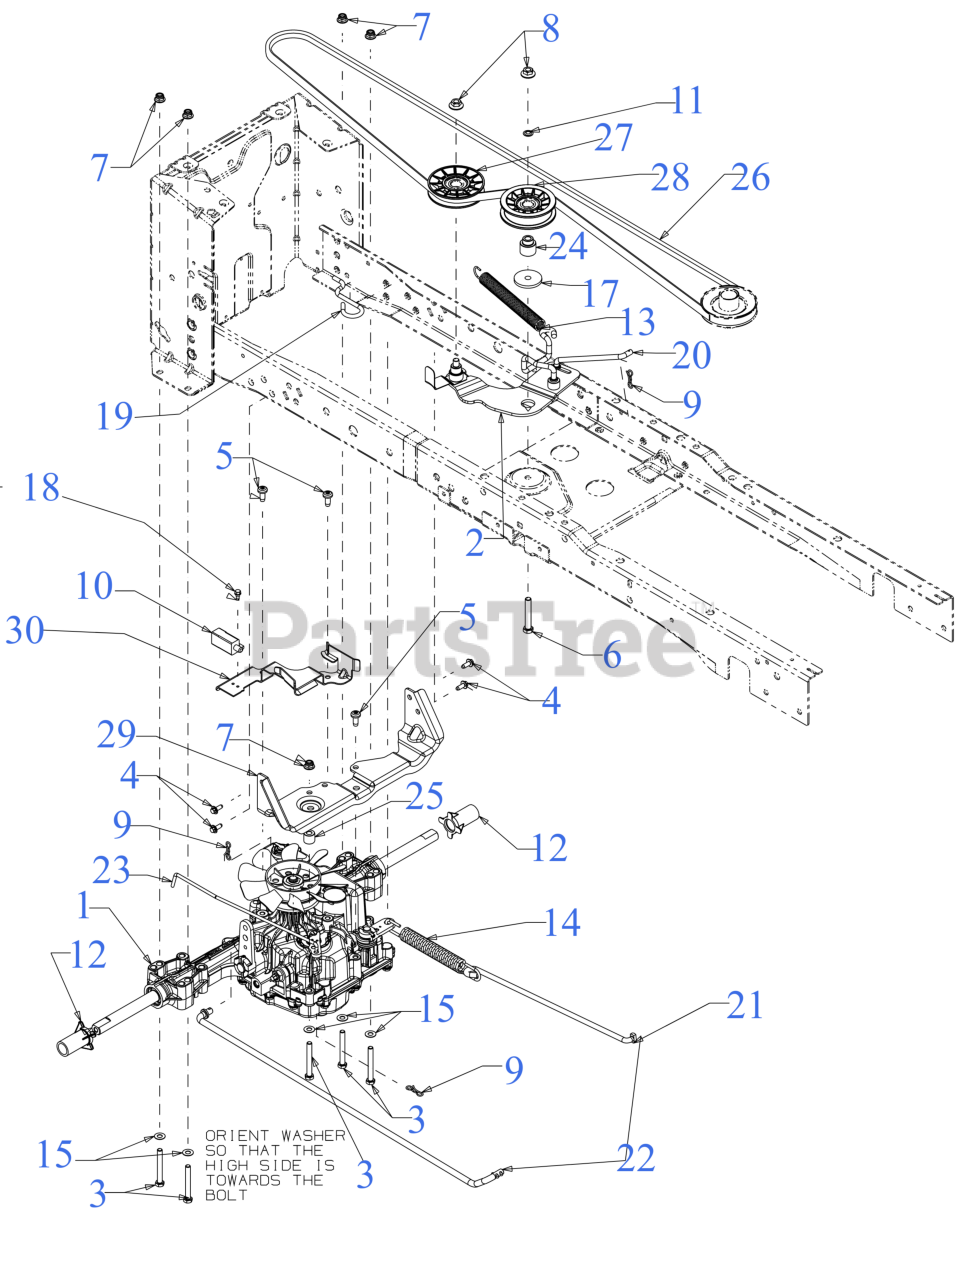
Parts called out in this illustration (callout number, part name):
1	HYDRO TRANSMISSION
2	IDLER BRACKET ASSEMBLY
3	SCREW 5/16-18 x 2.5 GR 5
4	SCREW M6-1 x .625
5	SCREW 5/16-18 x .750
6	SCREW 3/8-16 x 2.25 GR5
7	FLANGE LOCK NUT 5/16-18
8	FLANGE LOCK NUT
9	BOW TIE COTTER PIN 1/4-5/16
10	INTERLOCK SWITCH (NO/NC)
12	AXLE SLEEVE .765 ID x 2.11 LG
13	EXTENSION SPRING .790 DIA x 8.41
14	EXTENSION SPRING 0.90 DIA x 8.14
15	FLAT WASHER
17	SHOULDER SPACER
18	SHOULDER SCREW
19	DECK SPRING HOOK
20	IDLER BRACKET ROD
22	HYDRO CONTROL ROD
23	HYDRO DISENGAGEMENT ROD
24	SHOULDER SPACER
25	SPACER .34 x .75 x .63 LG
26	V-BELT A SEC x 90.90
27	V-IDLER PULLEY 3.56 OD
28	FLAT IDLER PULLEY 3.00 OD
29	TRANSMISSION MOUNTING BRACKET
